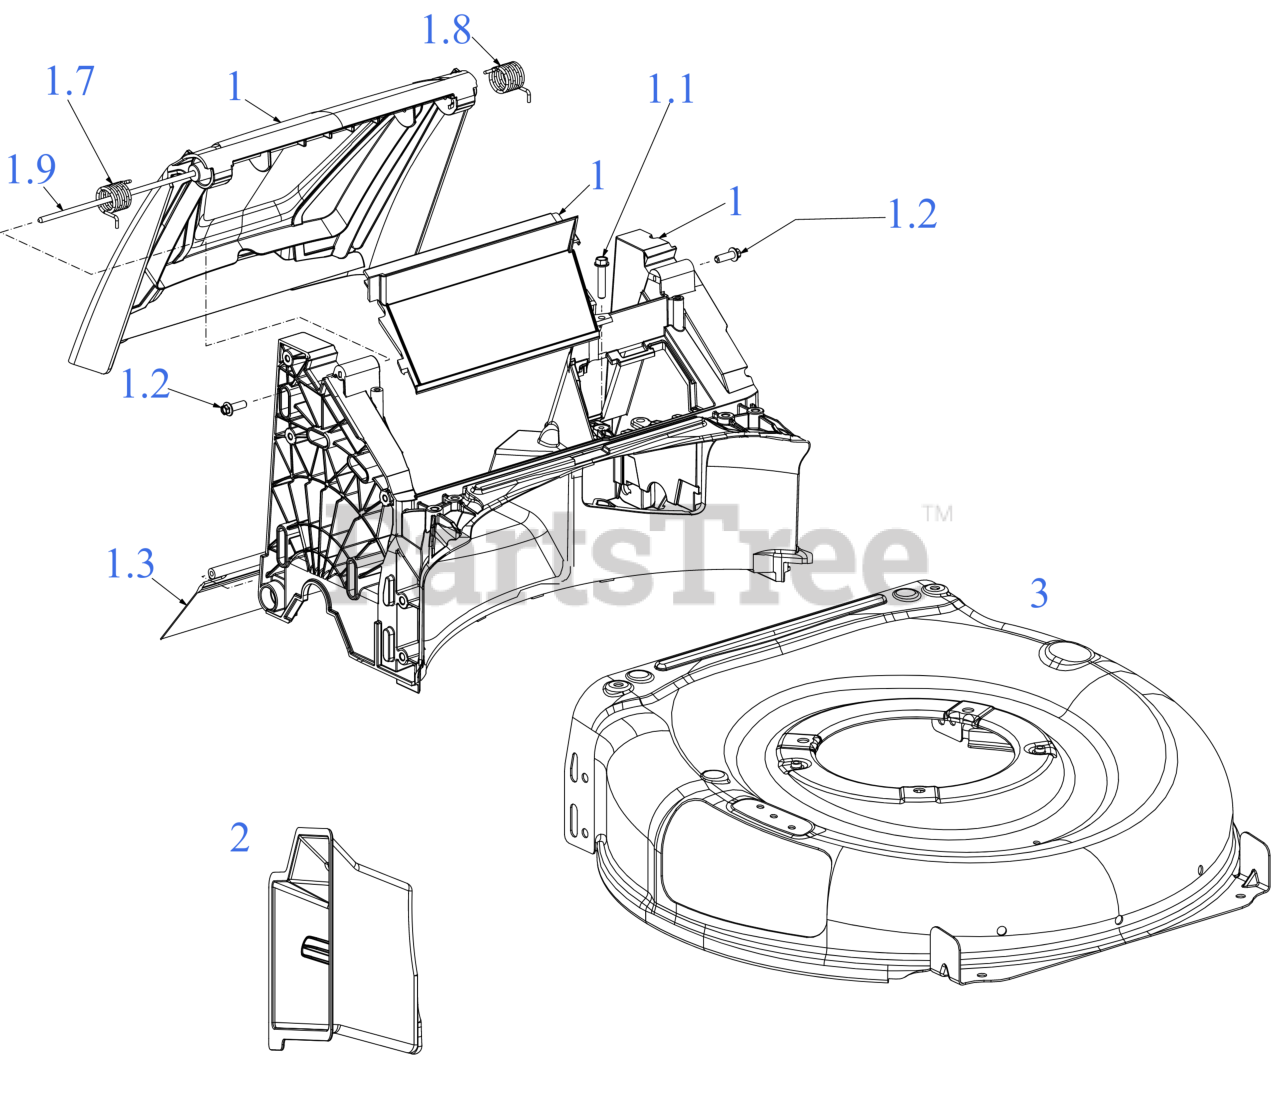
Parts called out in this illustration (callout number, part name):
1	REAR BAFFLE 21"
1.1	SCREW 1/4-15 x 1.250
1.2	SCREW 1/4 x .750
1.3	TRAILSHIELD
1.7	TORSION SPRING (RH)
1.8	TORSION SPRING (LH)
1.9	REAR DOOR PIVOT ROD
2	MULCH PLUG
